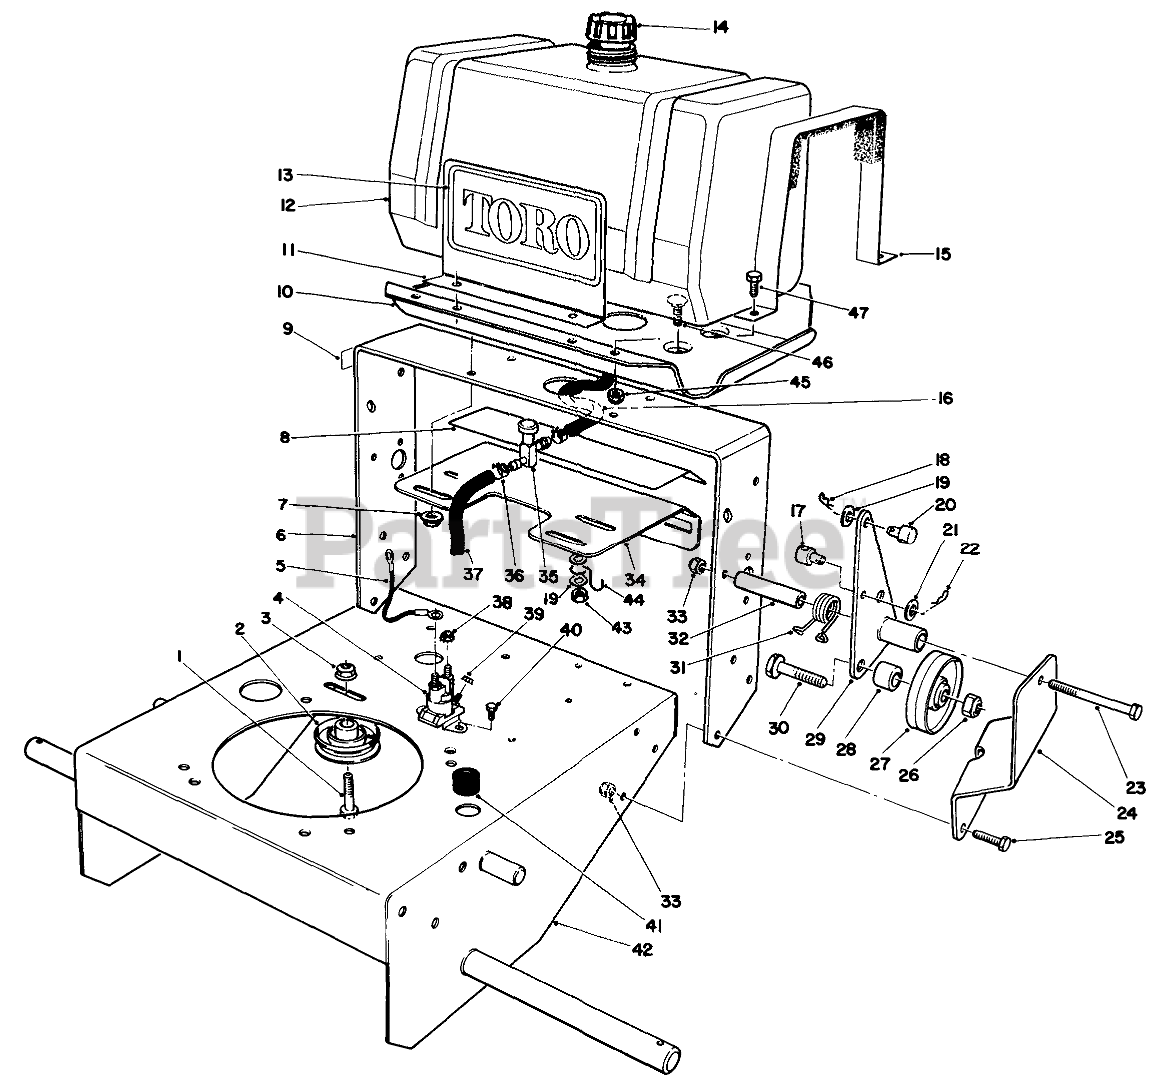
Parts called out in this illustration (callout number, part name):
1	SCREW-HH
2	PULLEY-IDLER
3	NUT-HF
4	Solenoid
5	WIRE-SOLENOID/STARTER
6	Frame-Rear
7	NUT-HF
8	Decal-Ground Speed
9	Decal-Fuel Shut Off
10	PLATE-FUEL TANK
11	DECAL-PLATE
12	TANK-FUEL
13	DECAL
14	GAS CAP ASM
15	STRAP ASM
16	HOSE-FUEL
17	ROD FITTING
18	PIN-COTTER
19	WASHER-PLAIN
20	ROD FITTING
21	WASHER-PLAIN
22	PIN-COTTER
23	SCREW-HH
24	Support-Idler L.H.
25	SCREW-HH
26	NUT-LOCK, NI
27	IdlerWheel
28	WHEEL IDLER SPACER
29	LH IDLER BRKT WA
30	SCREW-LEVELER
31	SPRING-TORSION, LH
32	PIVOT-IDLER SPACER
33	NUT-LOCK, NI
34	CONTROL PLATE R
35	FUEL VALVE
36	CLAMP-HOSE
37	GAS HOSE
38	NUT-KEPS
39	NUT-KEPS
40	SCREW
41	GROMMET
42	Frame
43	NUT-LOCK, NI
44	GAS LINE CLIP
45	NUT-LOCK, NI
46	SCREW-CARR
47	SCREW-HH
